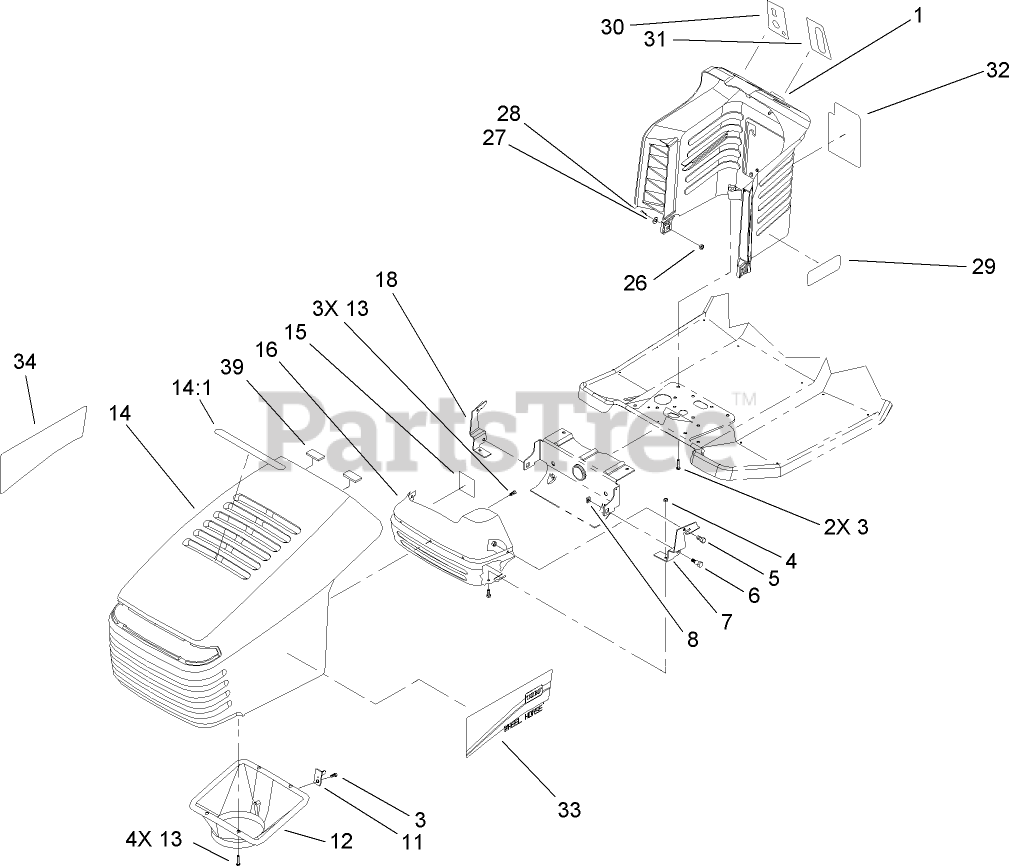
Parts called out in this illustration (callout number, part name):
1	TOWER-STEERING
3	SCREW-HWH
4	NUT-LOCK, NI
5	SCREW-HH
6	BOLT-SHOULDER
7	BRACKET-PIVOT, LH HOOD
8	NUT-RETAINER
11	LATCH-PIN
12	DUCT-AIR, HOOD
13	SCREW-PLASTITE
14	HOOD ASM
14:1	DECAL-AIR DUCT
15	PICK AS EACH
16	SHIELD-HEAT
18	BRACKET-PIVOT, RH HOOD
26	NUT-LOCK, NI
27	WASHER-PLAIN
28	SCREW-HH
30	DECAL-IGNITION/LIGHTS
31	DECAL-THROTTLE/CHOKE
32	DECAL-DANGER
33	DECAL-HOOD
34	DECAL-HOOD
39	FOAM-HOOD
